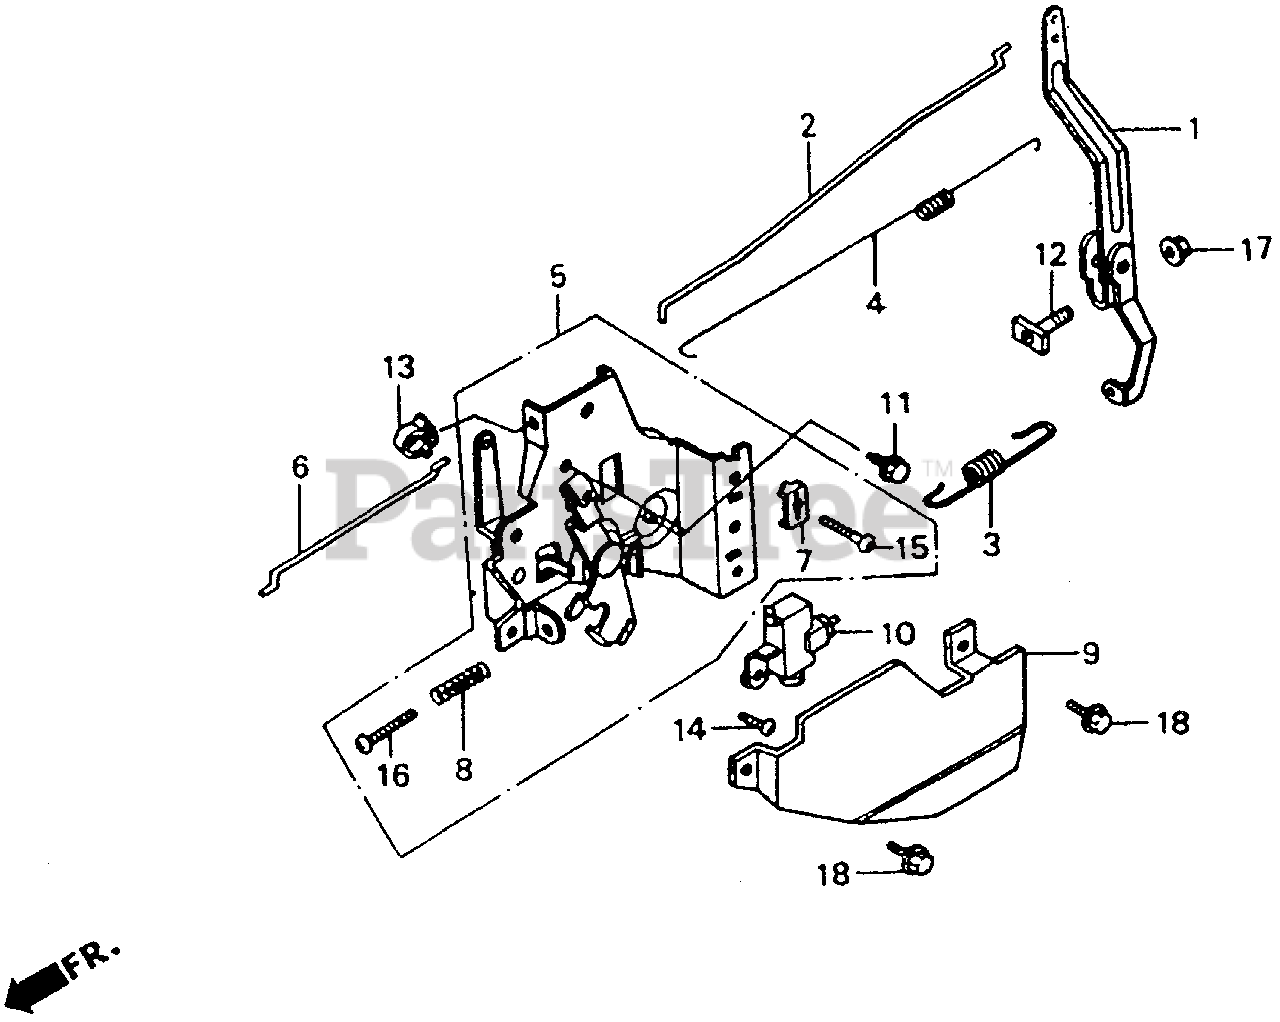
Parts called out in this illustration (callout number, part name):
1	ARM, GOVERNOR
2	ROD, GOVERNOR
3	SPRING, GOVERNOR
3	SPRING, GOVERNOR (STD)
4	SPRING, THROTTLE RETURN
5	CONTROL ASSY.
5	CONTROL
6	ROD, CHOKE
7	HOLDER, CABLE
8	SPRING, CONTROL ADJUSTING Use from Engine SN 2327377.
9	PROTECTOR, CONTROL
10	SWITCH ASSY., ENGINE STOP
11	BOLT, FLANGE (6X12) (CT200)
12	BOLT, GOVERNOR ARM
13	CLIP, WIRE HARNESS
14	SCREW, PAN (4X8)
15	SCREW, PAN (5X16)
16	SCREW, PAN (5X20)
17	NUT, FLANGE (6MM)
18	BOLT, FLANGE (6X10)
